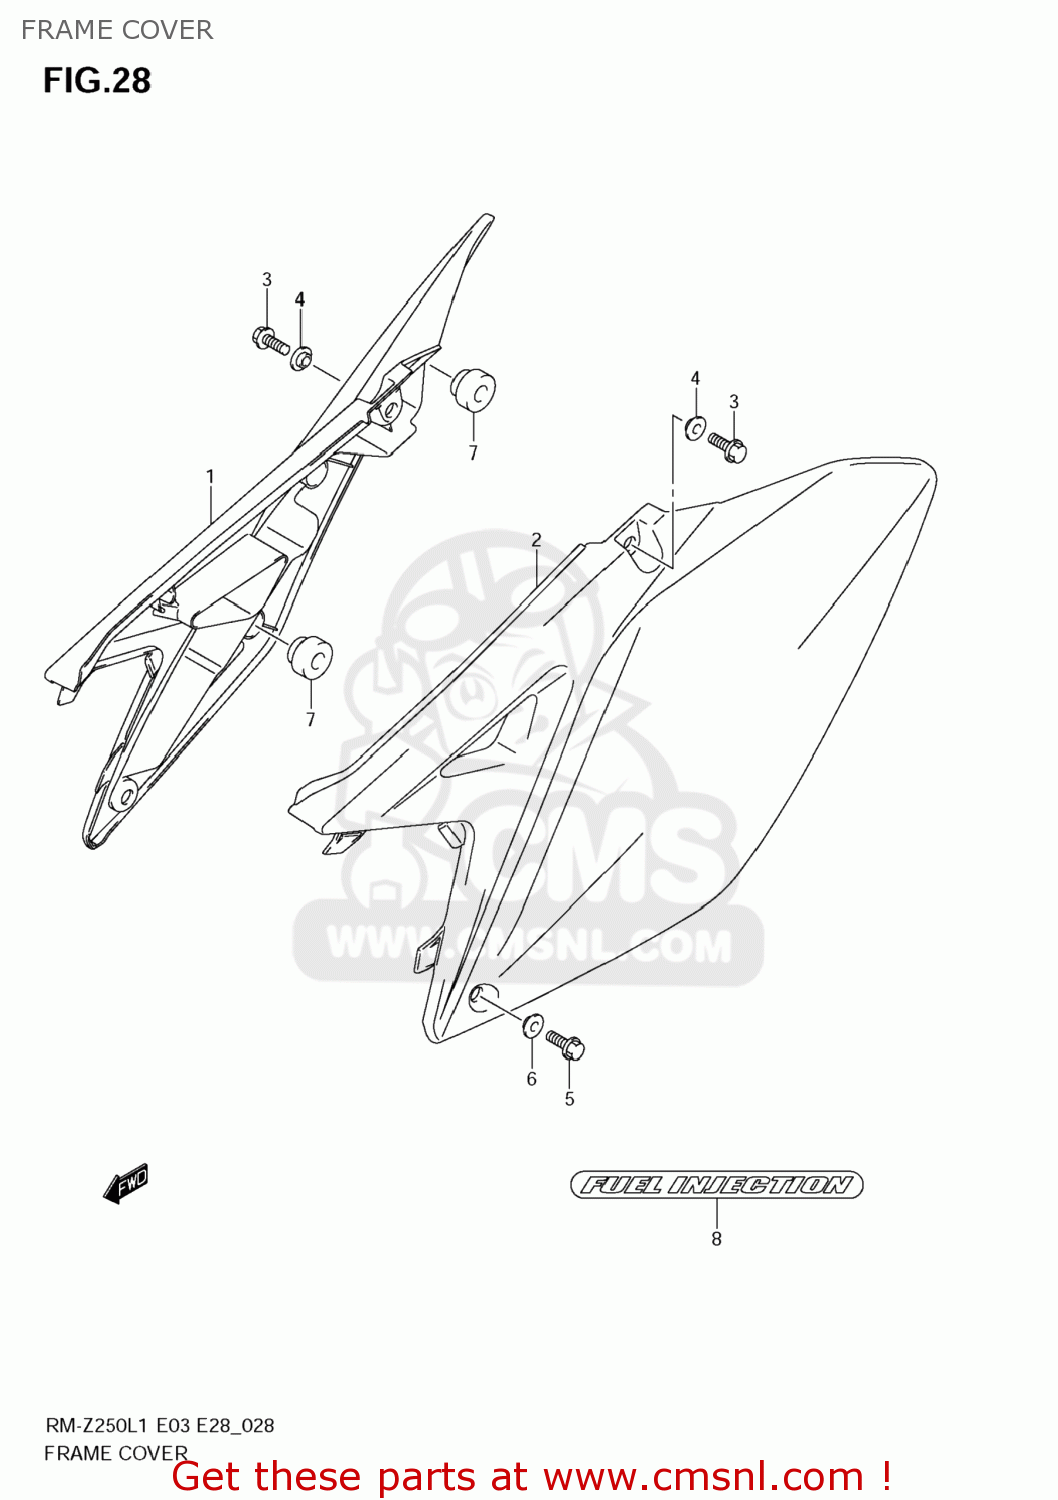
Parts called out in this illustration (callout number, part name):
1	COVER,FRAME,R
2	COVER,FRAME,L
3	BOLT
4	WASHER
5	BOLT(6X16)
6	WASHER
7	CUSHION
8	EMBLEM,FRAME COVER
